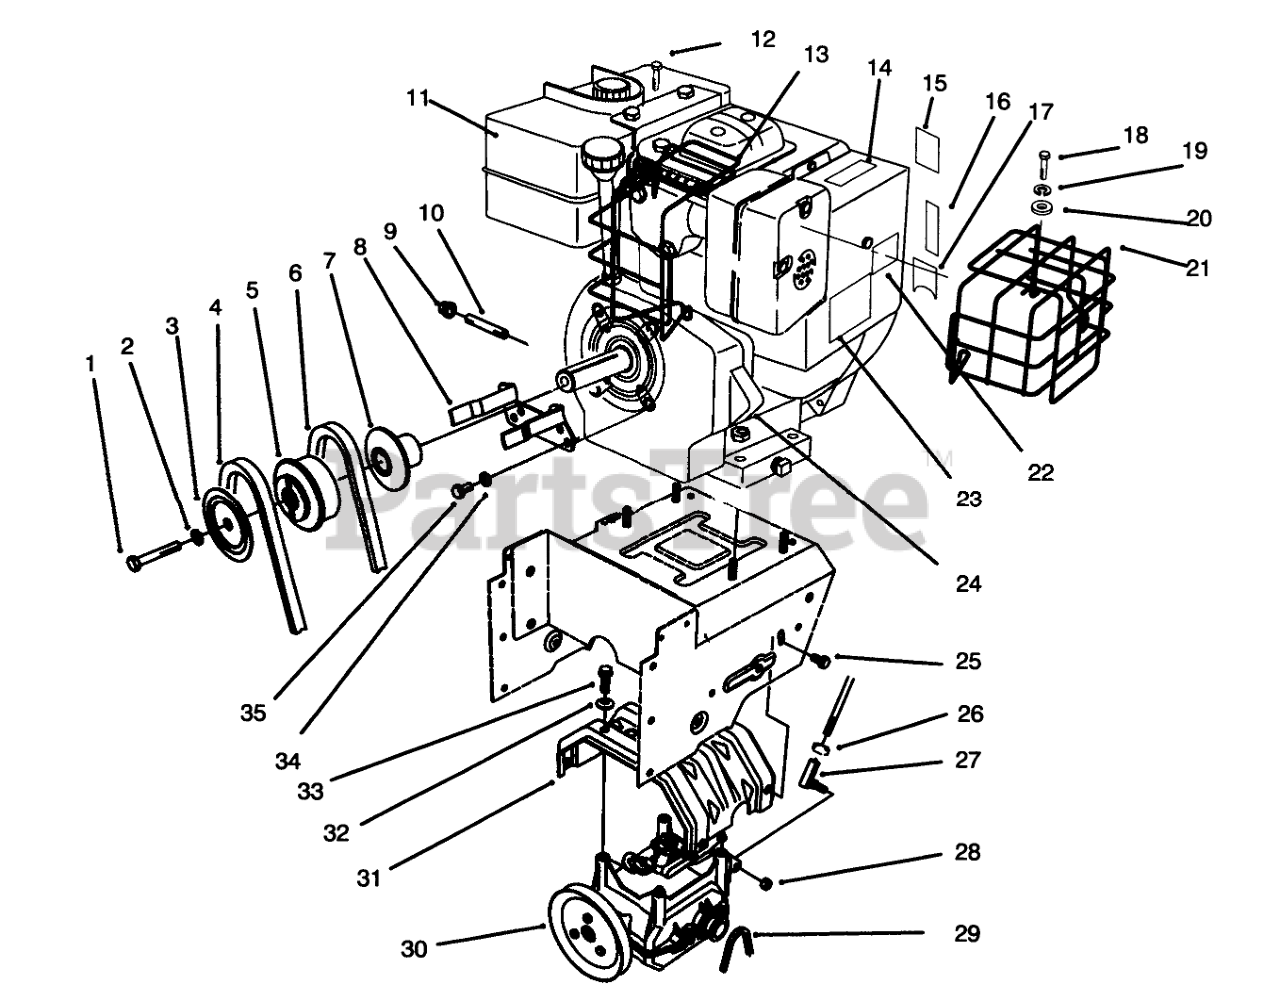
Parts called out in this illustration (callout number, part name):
1	SCREW-HH
2	WASHER-LOCK
3	SHEAVE-HALF, IMPELLER
4	V-BELT
5	PULLEY-ENGINE, CENTER
6	V-BELT, TRACTION
7	SHEAVE-HALF, TRACTION
8	Guide-Belt
9	CAP-PIPE
10	NIPPLE-PIPE
12	Screw/washer
13	Guard-Muffler
14	DECAL-HOT SURFACE, WARNING
15	DECAL - PRIMER
16	DECAL - THROTTLE, INT'L
17	DECAL - CHOKE
18	SCREW (only on: 38053)
19	Washer-Lock
20	Washer-Flat
21	Guard-Muffler, Model 38591
22	DECAL-WARNING, HOT SURFACE
23	DECAL-SURFACE, HOT
24	NUT-HF
25	SCREW-HHF
26	SCREW-CARR
27	JOINT-BALL
28	NUT-LOCK, NI
29	CHAIN
30	TRACTION GEARCASE ASM
31	Frame-Transmission
32	WASHER-SPRING
33	SCREW-HWHTF
34	WASHER-LOCK
35	SCREW-HH
